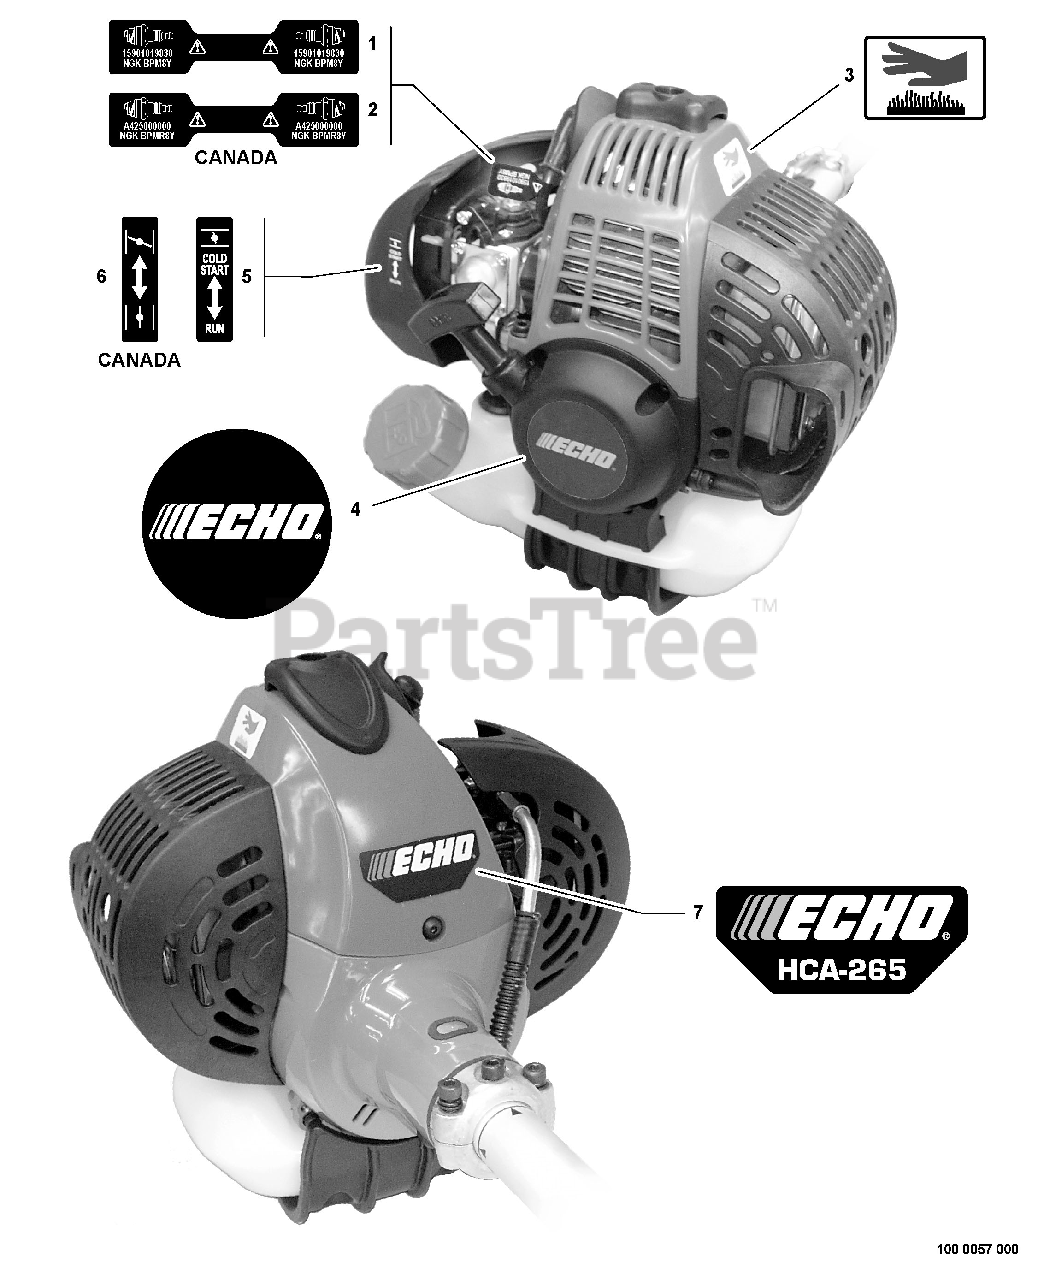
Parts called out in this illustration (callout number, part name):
1	LABEL - SPARK PLUG -- BPM-8Y
2	LABEL - SPARK PLUG -- BPMR-8Y
3	LABEL - HOT SURFACE
4	LABEL - ECHO
5	LABEL - CHOKE
6	LABEL - CHOKE
7	LABEL - MODEL HCA-265
